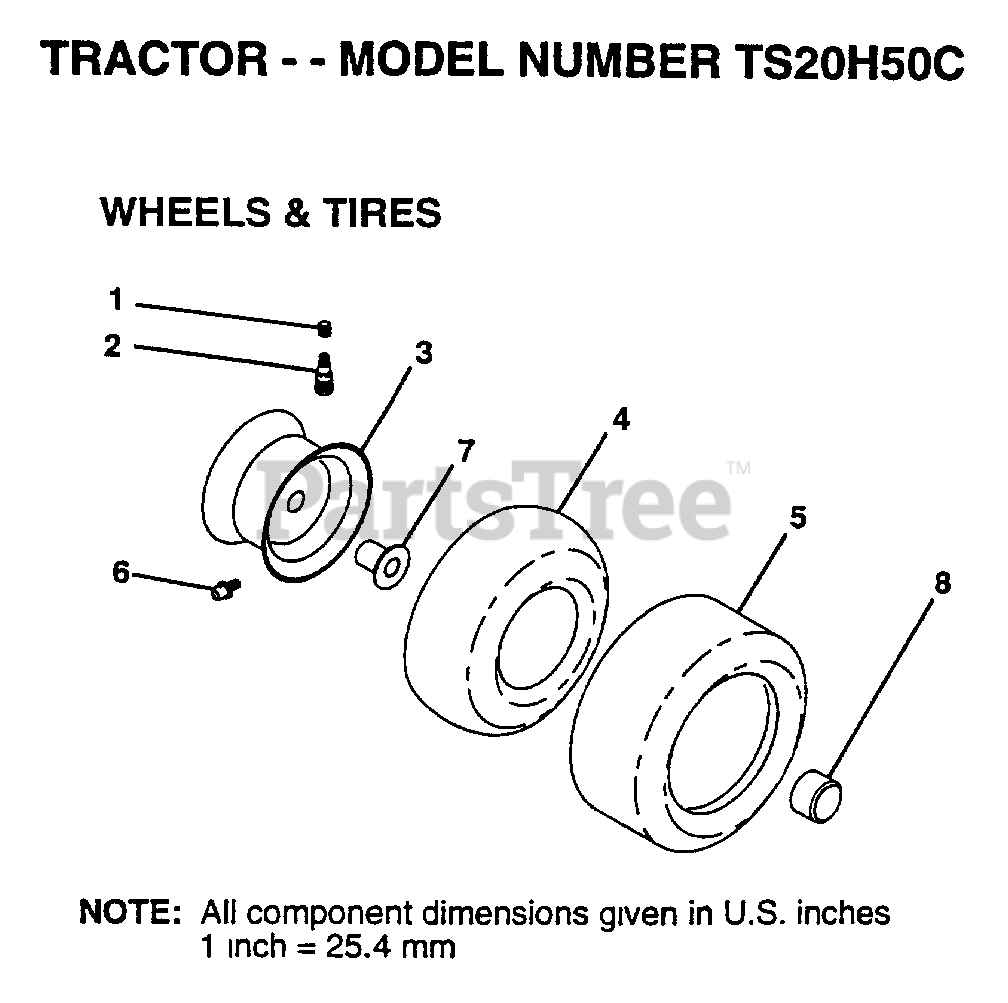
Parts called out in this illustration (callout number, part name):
1	VALVE CAP
2	VALVE STEM LT
3	RIM.FRONT.
4	TUBE.16X6.5/7.5-8
6	ZERK FITTING M
7	"FLANGE, BEARING"
8	HUB CAP
